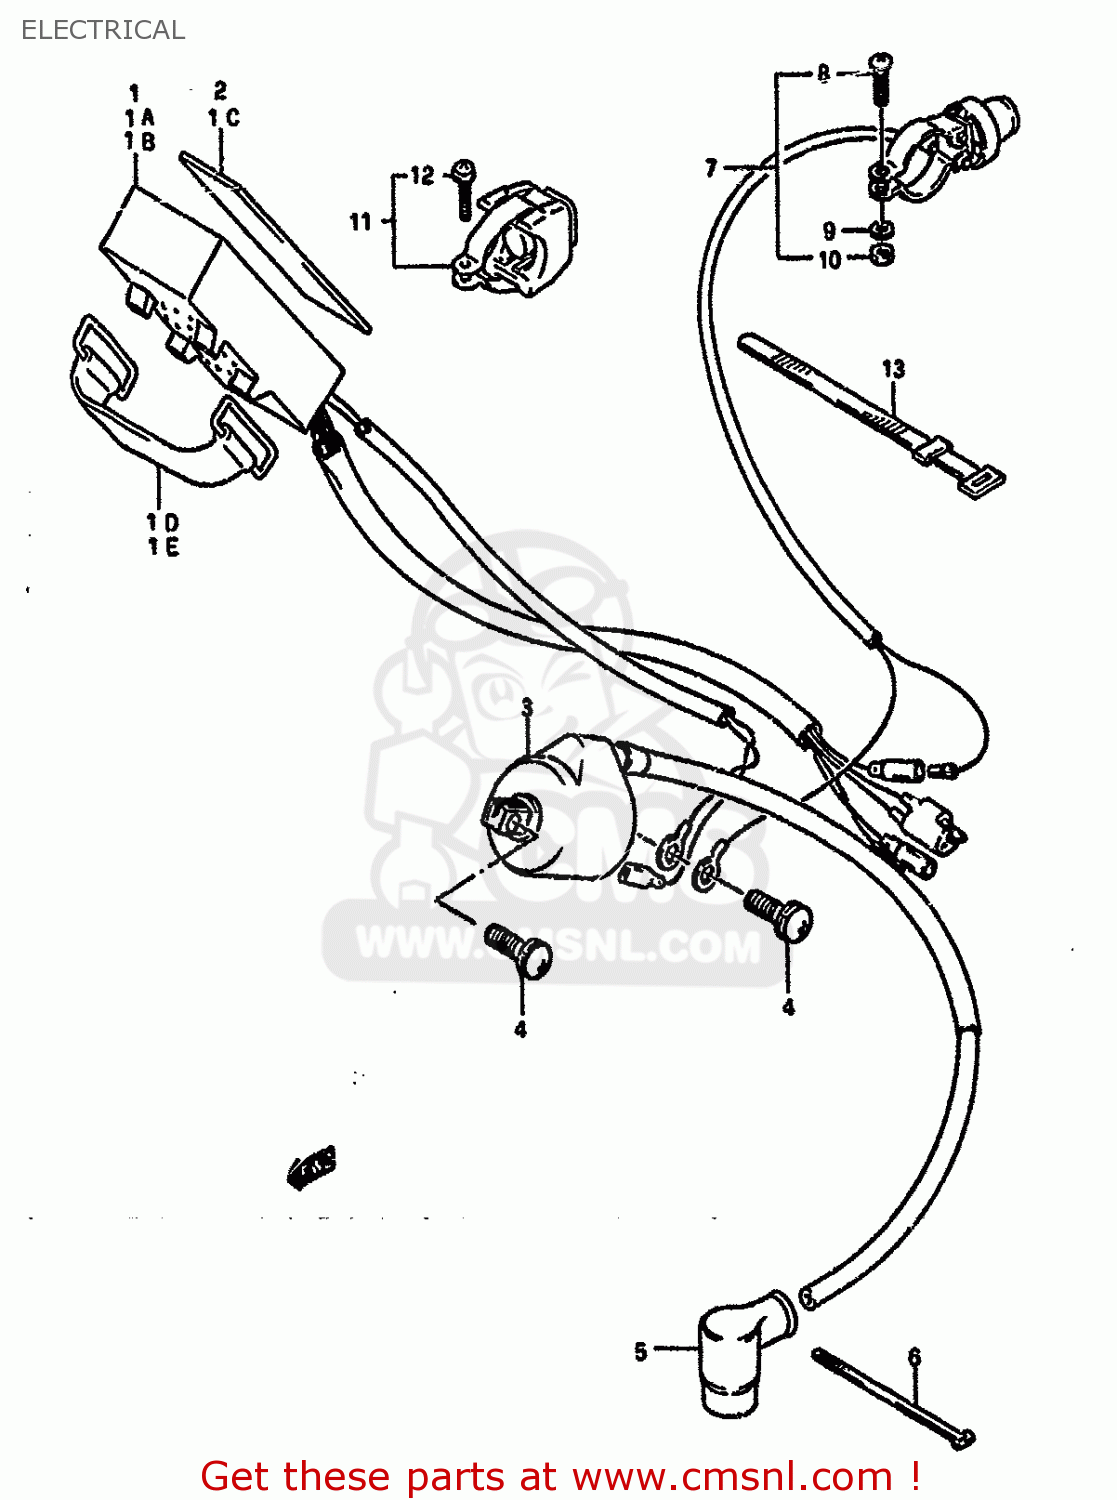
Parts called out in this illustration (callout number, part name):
1	CDI UNIT
1A	CDI UNIT
1B	CDI UNIT
1C	PROTECTOR(170X95X3.0)
1D	BAND
1E	BAND(L:65)
2	PROTECTOR(170X95X3.0)
3	COIL ASSEMBLY,IGNITION
4	SCREW
5	CAP,SPARK PLUG
6	CLAMP
7	SWITCH ASSEMBLY
8	SCREW
9	WASHER,LOCK 4M
10	NUT
11	SWITCH ASSEMBLY
12	SCREW
13	CLAMP(L:120)
